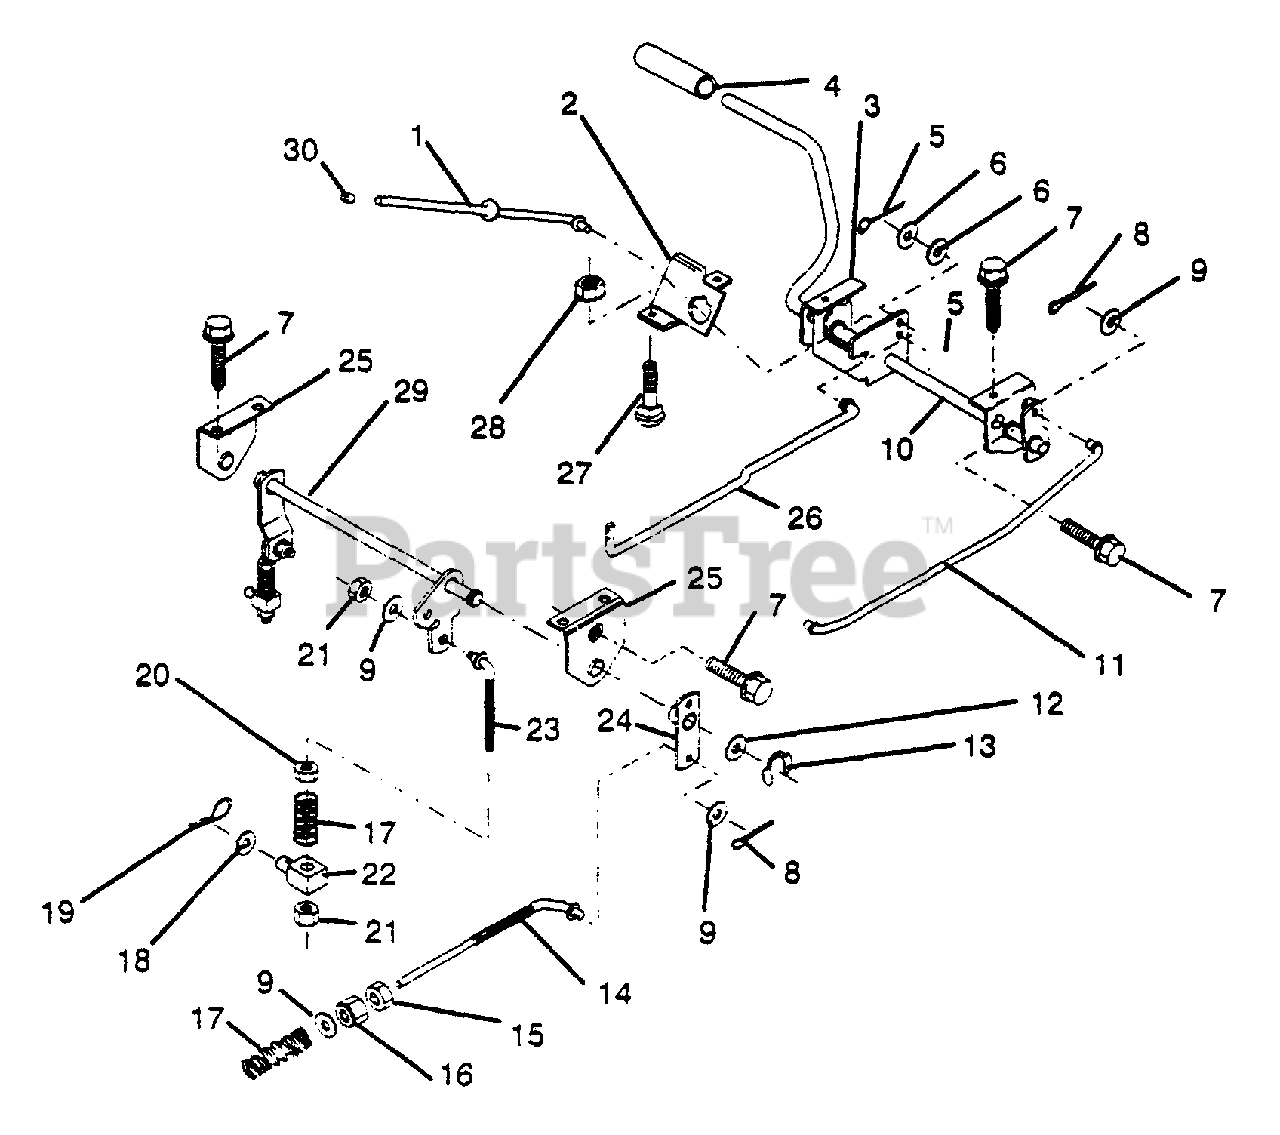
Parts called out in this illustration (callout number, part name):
1	Rod, Parking Brake
2	Bracket, Parking Brake
3	Bracket, L.H. Clutch Pedal
4	Cover, Pedal
5	Pin, Cotter 3/32 x 3/4
6	Washer, 13/32 x 5/8 x 16 Ga.
7	Screw, Hex Washer Hd. TF 5/16-18 x 1/2
8	Pin, Cotter 1/8 x 3/4
9	Washer 13/32 x 13/16 x 16 Ga.
10	Assembly, Clutch/Brake Pedal
11	Rod, Front Brake
12	Washer 25/32 x 1-1/8 x 16 Ga.
13	Ring, Clip
14	Rod, Rear Brake
15	Nut, Hex Jam 3/8-16 UNC
16	Nut, Lock, Hex with Wsh Insert 3/8-16 UNC
17	Spring, Brake Rod
18	Washer 13/32 x 1 1/4 x 12 Ga.
19	Spring, Retainer
20	Nut, Centerlock 3/8-16 UNC
21	Nut, Crownlock 3/8-16 UNC
22	Trunnion, Lift
23	Link, Threaded
24	Assembly, Brake Pivot Arm
25	Bracket, Lift Shaft
26	Rod, Clutch
27	Bolt, Carriage 5/16-18 UNC x 3/4
28	Nut, Keps 5/16-18 UNC
29	Assembly, Rear Mower Lift
30	Cap, Plunger
